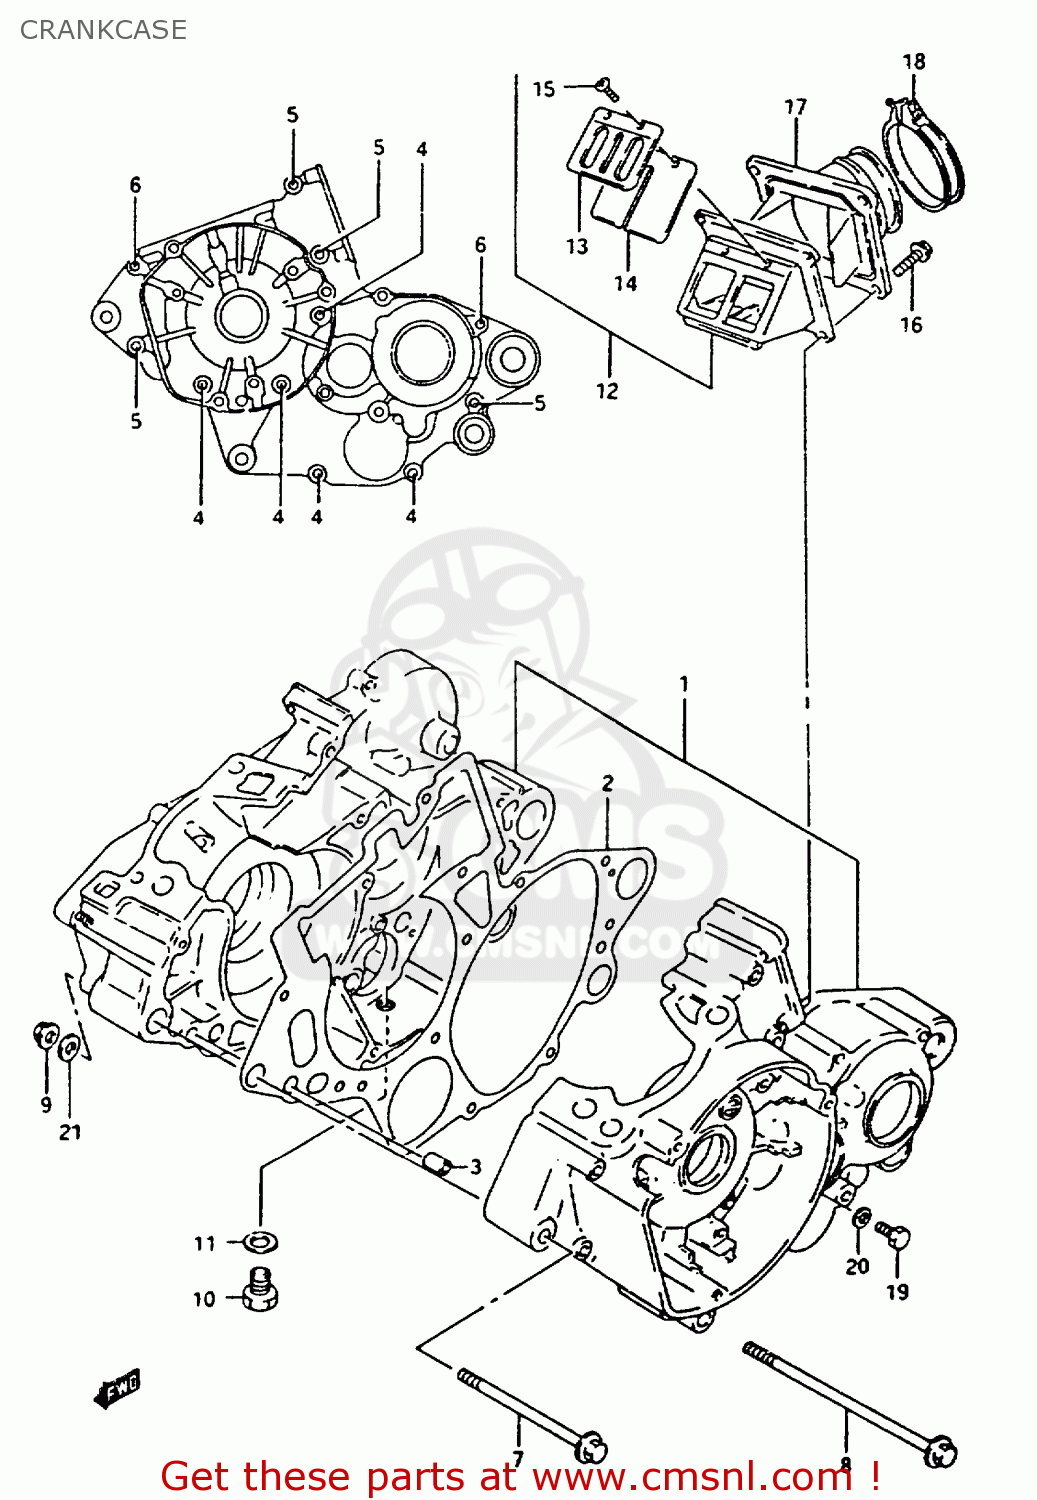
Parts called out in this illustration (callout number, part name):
1	CRANKCASE SET
2	GASKET,CRANKCASE (NAS)
3	PIN
4	BOLT
5	BOLT
6	BOLT
7	BOLT(8X88)
8	BOLT(8X125)
9	NUT
10	Bolt
11	GASKET(12.1X16.2X3.7) (NAS)
12	VALVE ASSY,REED
13	STOPPER,REED VALVE
14	VALVE,REED
15	SCREW
16	BOLT
17	PIPE,INTAKE
18	CLAMP
19	SCREW(6X10)
20	GASKET(6.2X11X1).2 (NAS)
21	WASHER
